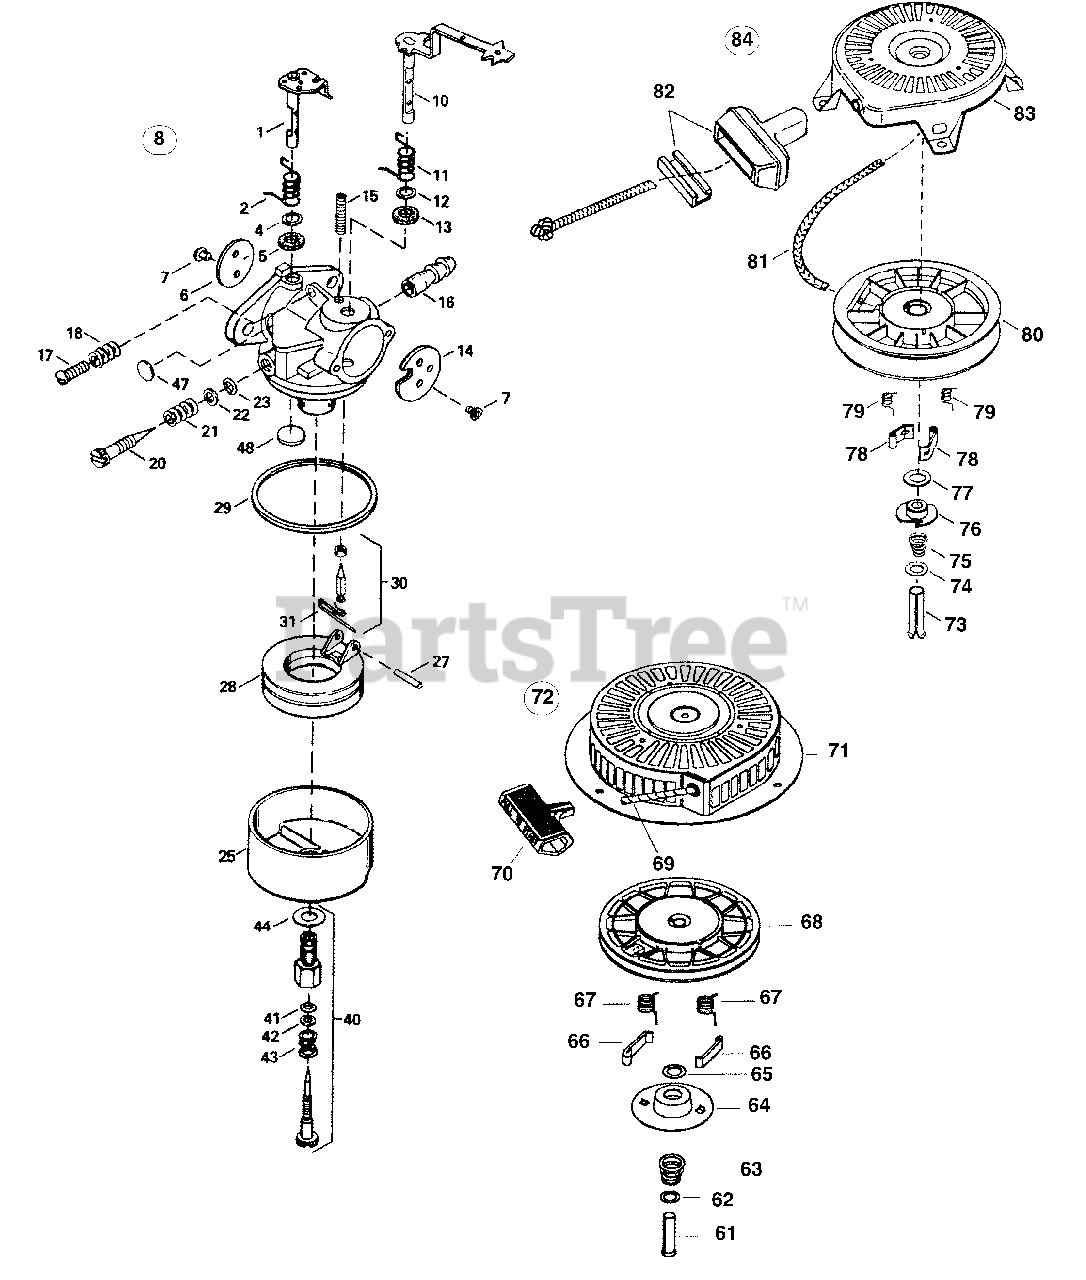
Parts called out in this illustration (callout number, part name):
1	Throttle Shaft & Lever Ass'y
2	Throttle Return Spring
4	Dust Seal Washer
5	Dust Seal (Throttle)
6	Throttle Shutter
7	Shutter Screw
8	Carburetor Ass'y
10	Choke Shaft & Lever Ass'y
11	Choke Return Spring
12	Dust Seal Washer
13	Dust Seal Choke
14	Choke Shutter
15	Choke Positioning Spring
16	Fuel Fitting
17	Throttle Crack/Idle Speed Screw
18	Tension Spring
20	Idle Mixture Screw
21	Tension Spring
22	Idle Mixture Screw Washer
23	Idle Mixture Screw "O" Ring
25	Float Bowl
27	Float Shaft
28	Float
29	Float Bowl "O" Ring
30	Inlet Needle, Seat & Clip
31	Spring Clip
40	Main Adjustment Screw Ass'y
41	High Speed Mixture Screw "O" Ring
42	High Speed Mixture Screw Washer
43	High Speed Mixture Screw Tension Spring
44	Bowl Nut Washer
47	Welch Plug, Idle Mixture Well
48	Welch Plug, Atmospheric Vent
61	Spring Pin
63	Brake Spring
66	Starter Dog
67	Dog Spring
68	Pulley & Rewind Spring Ass'y
69	Starter Rope (98")
70	Starter Handle
71	Starter Housing Ass'y
72	Rewind Starter Ass'y
73	Spring Pin
75	Brake Spring
78	Starter Dog
79	Dog Spring
80	Pulley & Rewind Spring Ass'y
81	Starter Rope (114")
82	Starter Handle
83	Starter Housing Ass'y
84	Recoil Starter Ass'y
